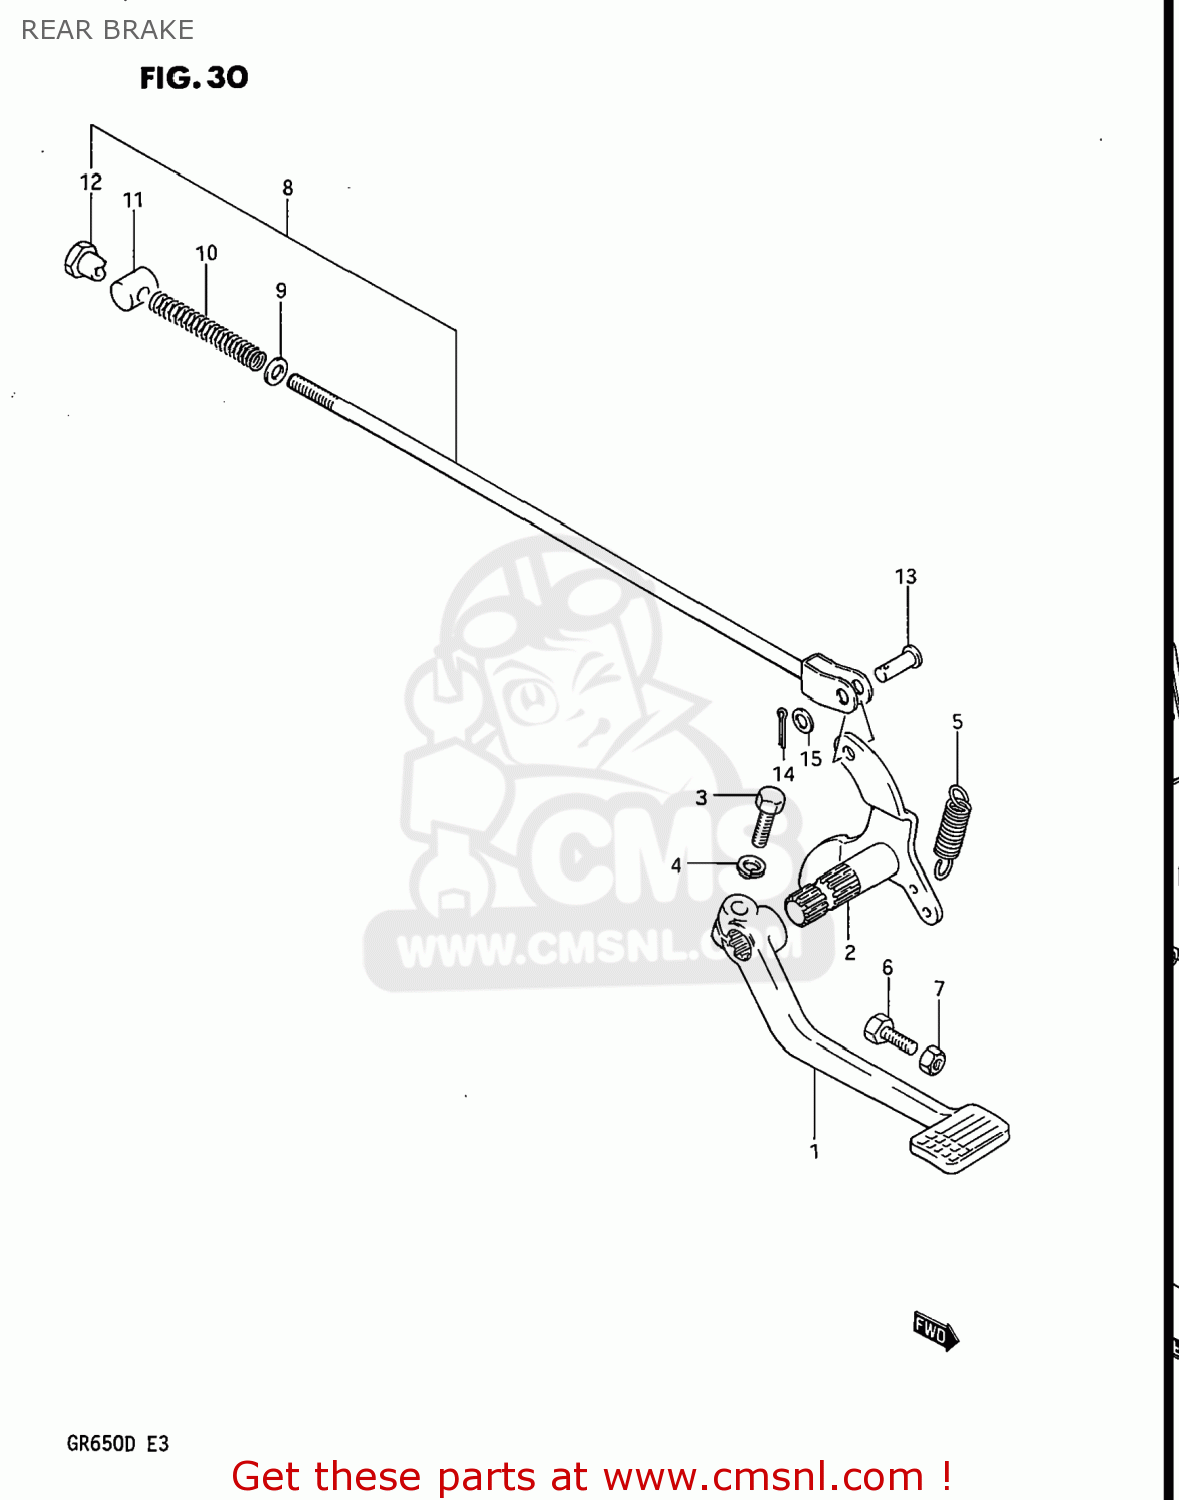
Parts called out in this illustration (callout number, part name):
1	PEDAL,BRAKE
2	ARM,BRAKE ROD
3	BOLT
4	LOCK WASHER
5	SPRING
6	BOLT(6X23)
7	NUT
8	ROD ASSEMBLY,REAR BRAKE
9	WASHER
10	SPRING
11	PIN
12	NUT (6MM)
13	PIN(L:13.5)
14	PIN 20X20
15	WASHER
